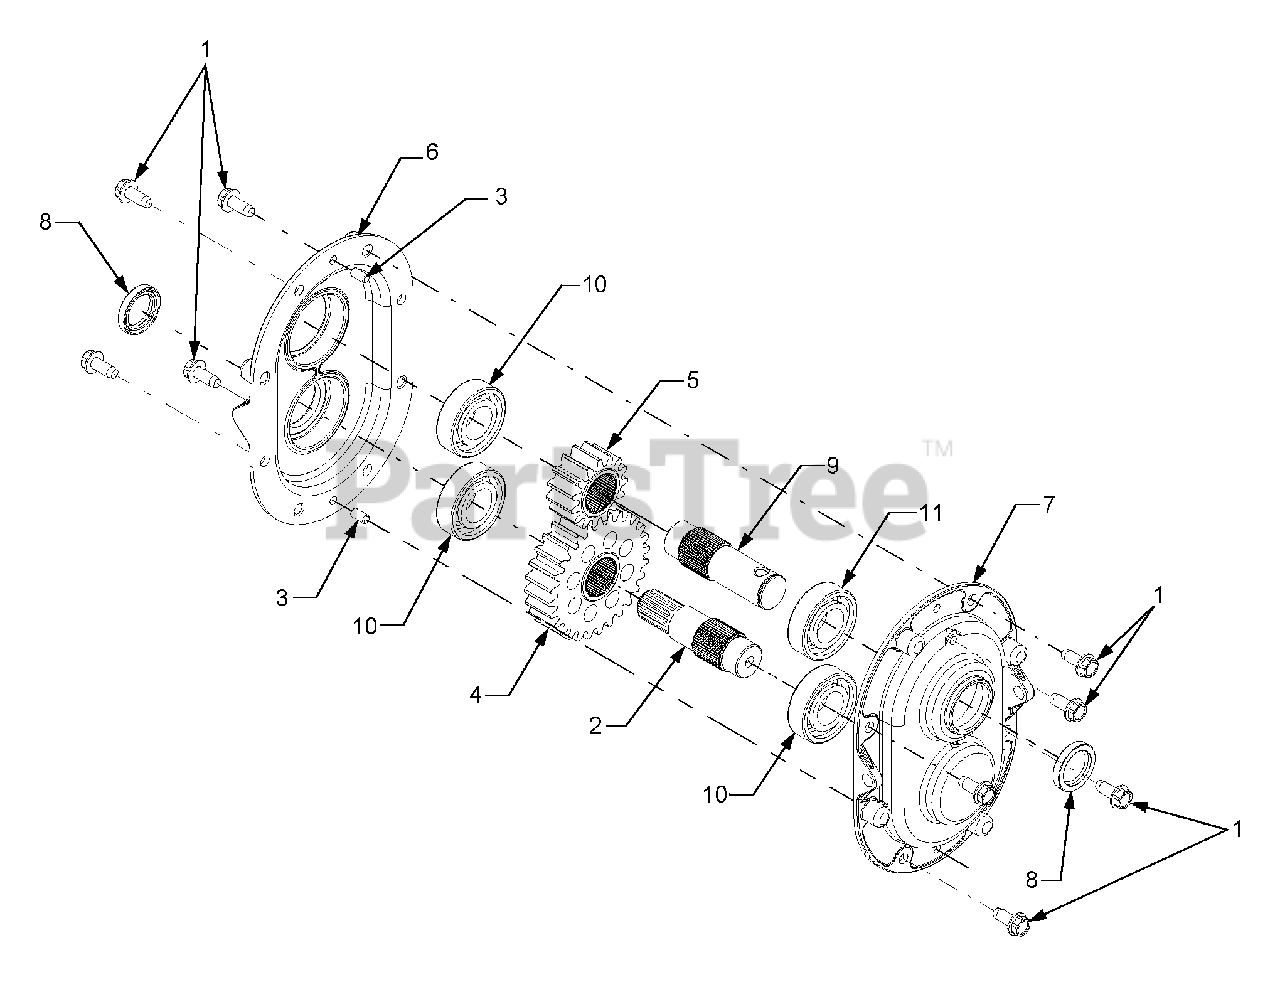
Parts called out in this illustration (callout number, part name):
1	Screw, Hex Wash. Hd. Tapp 5/16-18 x .75
2	Shaft, Output
3	Pin, Dowel, .25 x .5
4	Gear, Spur, 28T
5	Gear, Spur, 15T
6	Housing, Gear
7	Housing, Gear
8	Seal, Oil
9	Shaft, Input
10	Bearing, Ball
11	Bearing, Ball
